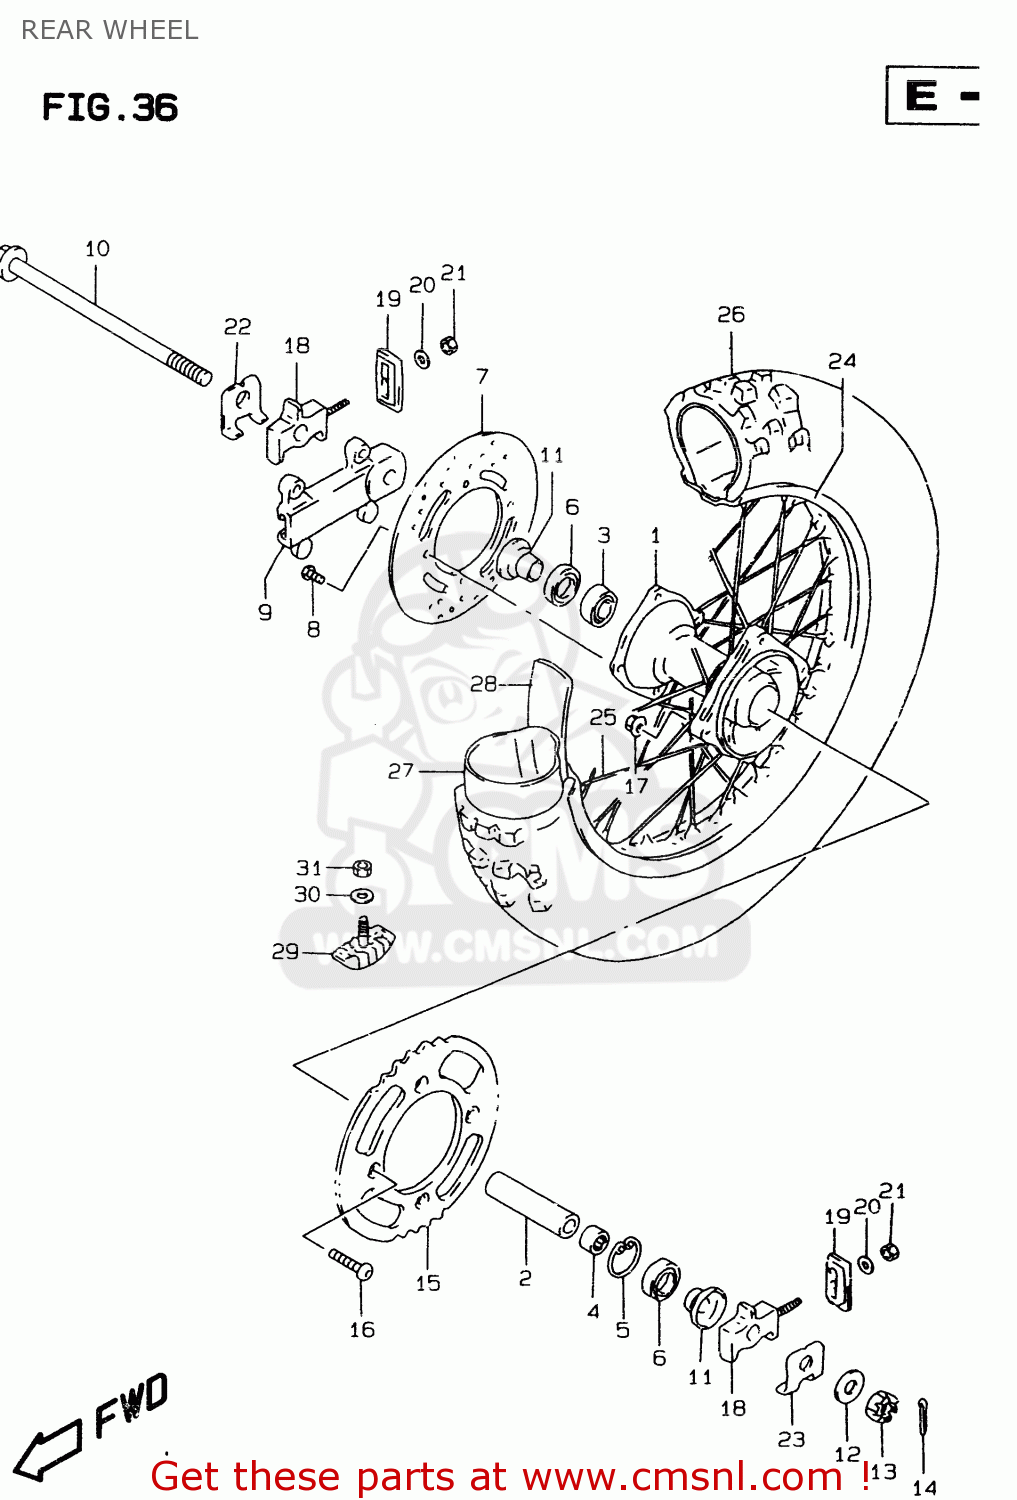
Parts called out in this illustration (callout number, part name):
1	HUB,RR WHEEL
2	SPACER,RR HUB BEARING
3	BEARING
4	BEARING(15X35X11)
5	CIRCLIP
6	SEAL,OIL(20X35X7)
7	DISC,REAR BRAKE
8	SCREW
9	BRACKET,RR AXLE
10	AXLE,RR
11	SPACER,RR AXLE
12	WASHER
13	NUT
14	COTTER PIN
15	SPROCKET,RR(49T)
16	BOLT(8X30.5)
17	NUT
18	ADJUSTER,CHAIN
19	PLATE,CHAIN ADJUSTER
20	WASHER
21	NUT 6MM
22	WASHER,CHAIN ADJUSTER RH
23	WASHER,CHAIN ADJUSTER,L
24	RIM,RR WHEEL(1.60X14 AL)
25	SPOKE ASSY,RR WHEEL
26	TIRE,RR(90/100 14)
27	TUBE ASSY,WHEEL INNER
28	PROTECTOR,WHEEL,INNER
29	STOPPER,BEAD(1.85)
30	WASHER
31	NUT
